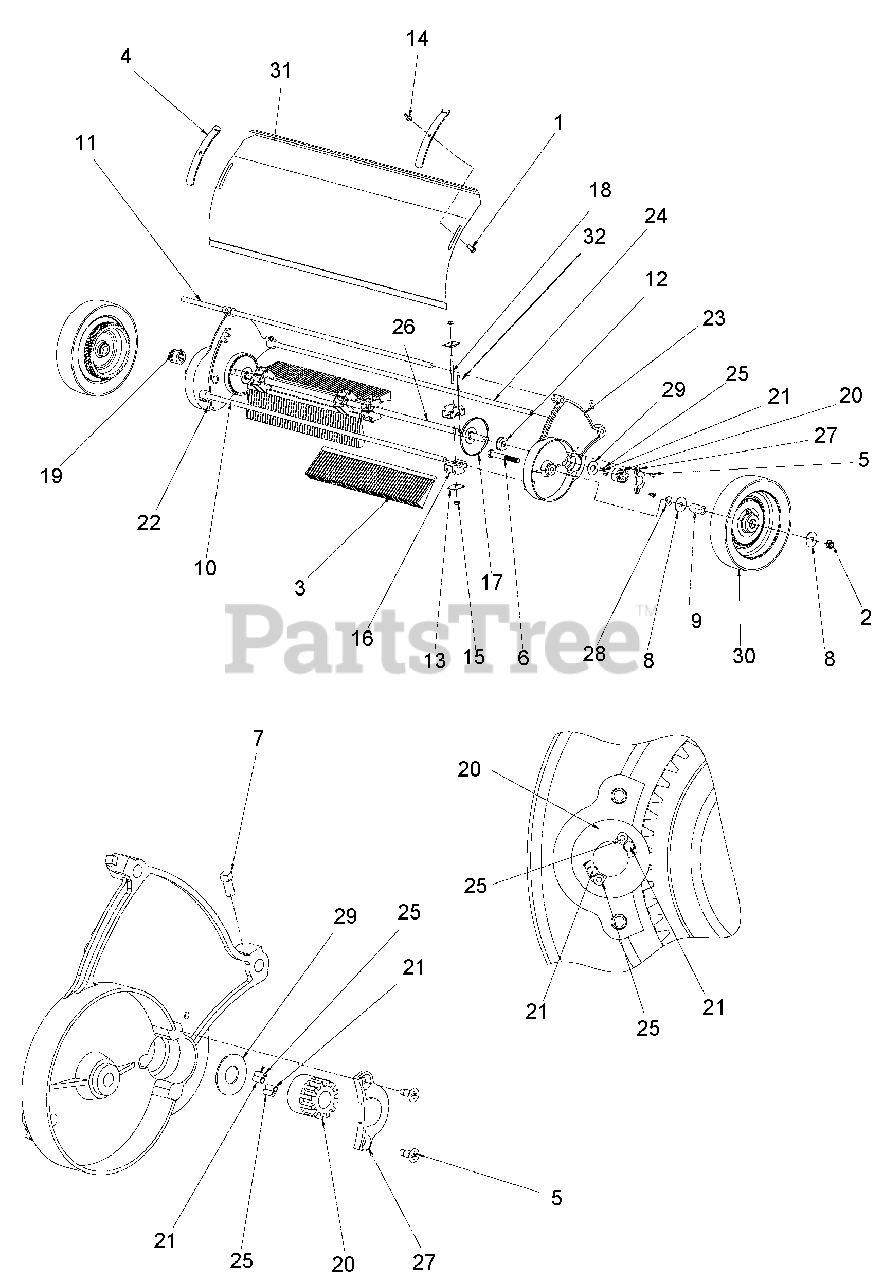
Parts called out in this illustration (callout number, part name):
1	Bolt, Hex .31-18 x 1.00 Hex 5
2	Nut, Locking Jam, Nyloc .50-20 Gr. 2 YWZC
3	Sweeper Brush
4	Hood Clamp
5	Screw, Flange Head .25-20 x .63 Self-Tapping
6	Bolt, 1/2-20 x 4 Axle
7	Set Screw, Square Head
8	Washer, .516 x 1.625 x .075 Felt
12	Bearing, Flange Radial
13	Clamp, Brush Strip
14	Wing Nut .321-18 YWZC
15	Nut, Spinlock .25-20 YWZC
17	Dust Cover
18	Stud, Zinc Plated
19	Pinion, Right
20	Pinion, Left
21	Dowel Pin, .1875 OD x .4375
22	Side Plate, Right
23	Side Plate, Left
24	Pivot Rod 43 1/8"
25	Pawl Spring
26	Reel Shaft, Plated
27	Cover Pinion
28	Washer, Fiber
29	Washer, .656 x 1.50 x .06 Fiber
30	Tire Assembly
31	Hood with Decals
32	Pin, Roll 3/16 x 1.0
